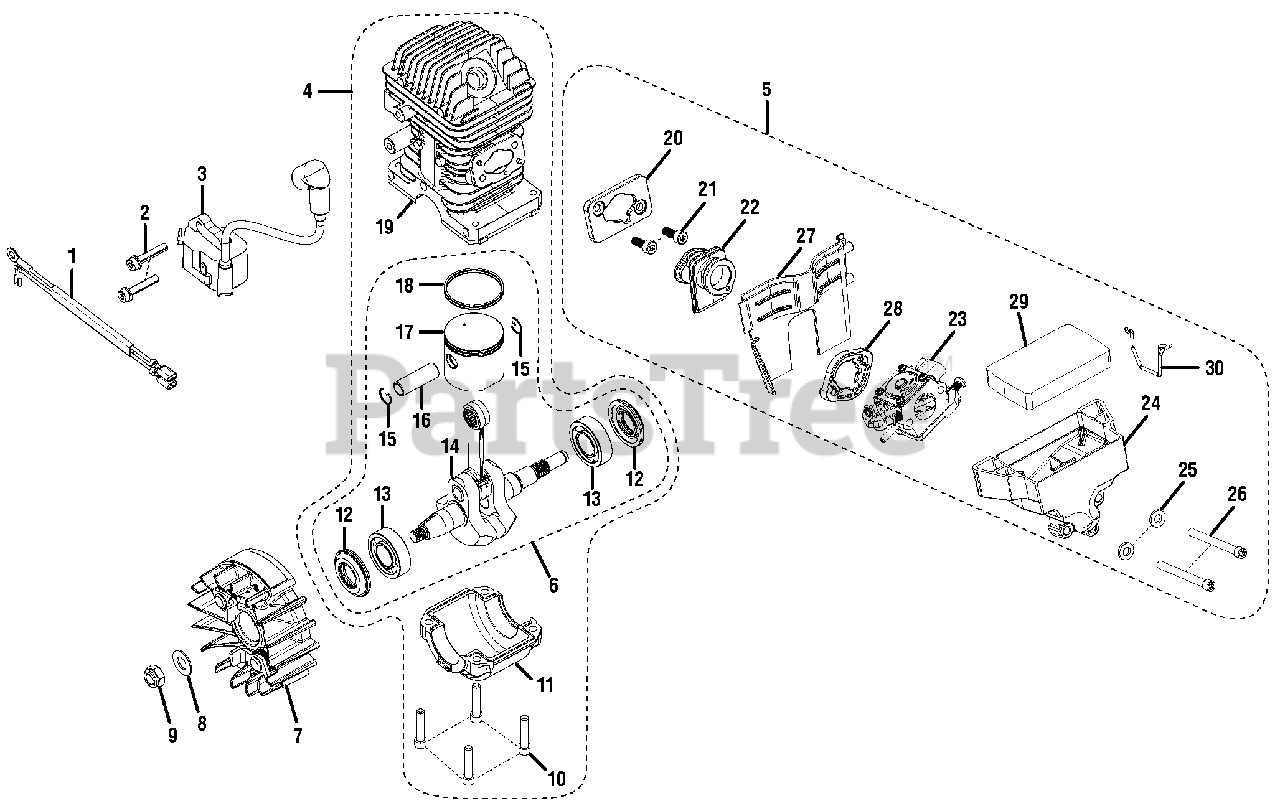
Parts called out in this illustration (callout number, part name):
1	Ignition Switch Harness
2	Bolt (M5 x 25.4 mm)
3	Ignition Module
4	Short Block Assembly
5	Intake Assembly
6	Crankshaft & Piston Assembly
7	Flywheel Assembly
8	Washer
9	Flywheel Nut
10	Screw (M5 x 24 mm)
11	Crankshaft Case
12	Crankshaft Seal
13	Ball Bearing
14	Crankshaft & Rod Assembly
15	Spring Retainer
16	Piston Pin
18	Piston Ring
20	Press Plate, Cylinder
21	Bolt (M5 x 14 mm)
22	Intake Boot
23	Carburetor
24	Air Filter Box
26	Bolt (M5 x 50 mm)
28	Press Plate, Carb
29	Air Filter
30	Throttle Rod
